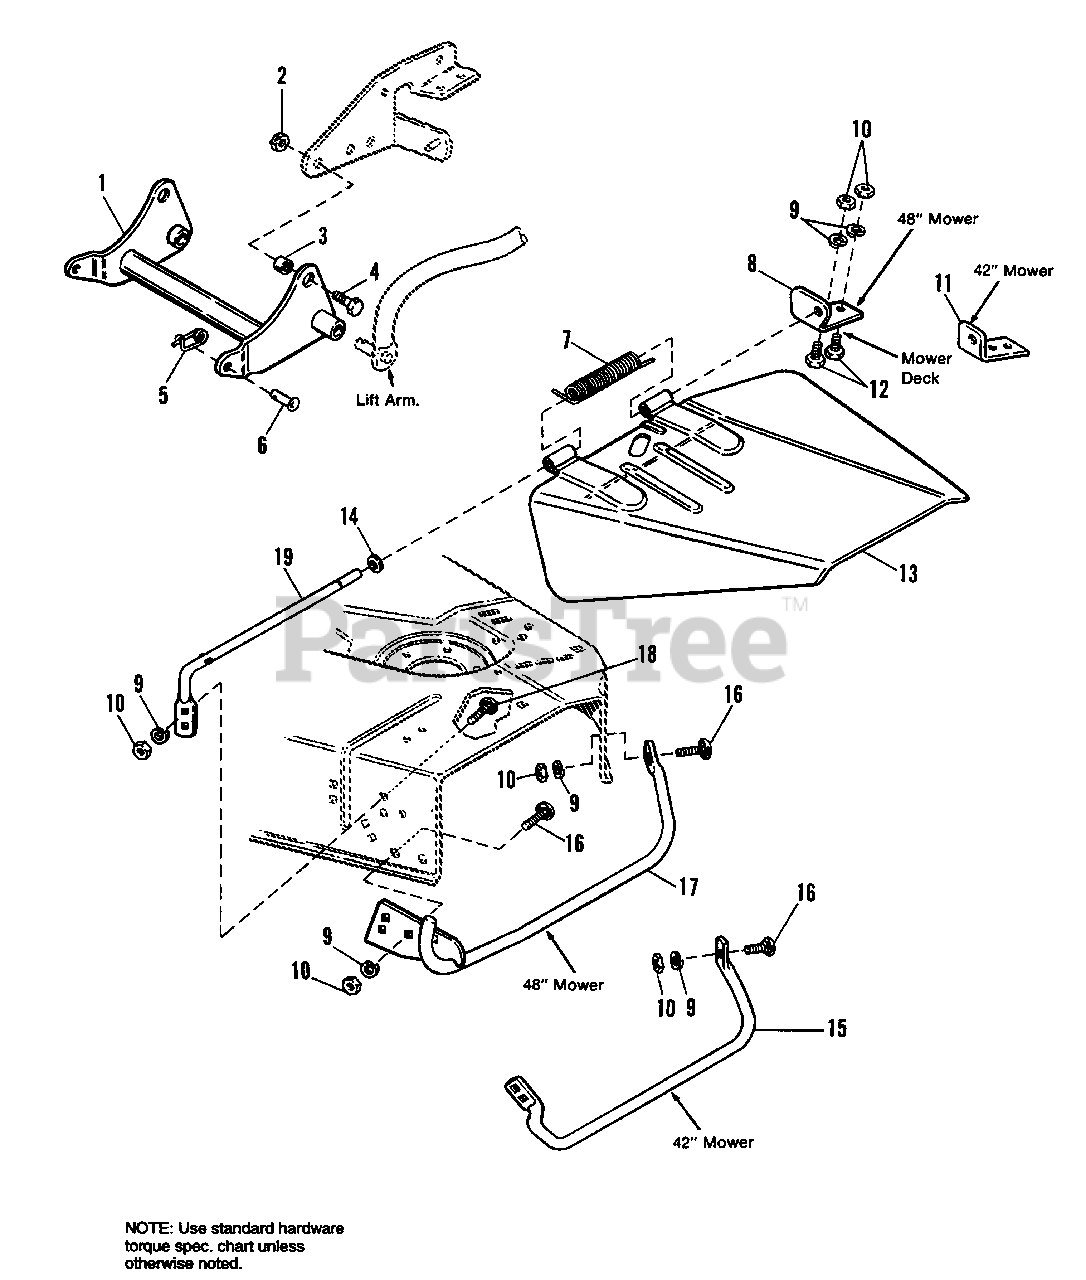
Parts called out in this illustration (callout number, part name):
1	ARM ASSY., Rocker
2	LOCKNUT, Hex, 1/2-13
3	SPACER
4	CAPSCREW, Hex, 1/2-13 x 1-1/4
5	CLIP, Pin, Safety
6	PAN, 3/8 x 1-1/2
7	SPRING, Torsion
8	BRACKET, Rod
9	LOCK WASHER, 3/8
10	NUT, Hex, 3/8-16
11	BRACKET, Rod
12	CAP SCREW, Hex, 3/8-16 x 1
13	DEFLECTOR ASSY.
14	WASHER, 7/16
15	STONE GUARD
16	BOLT, Carriage, 3/8-16 x 1
17	STONE GUARD ASSY.,
18	BOLT, Carriage, 3/8-16 x 7/8
19	ROD, Hinge
